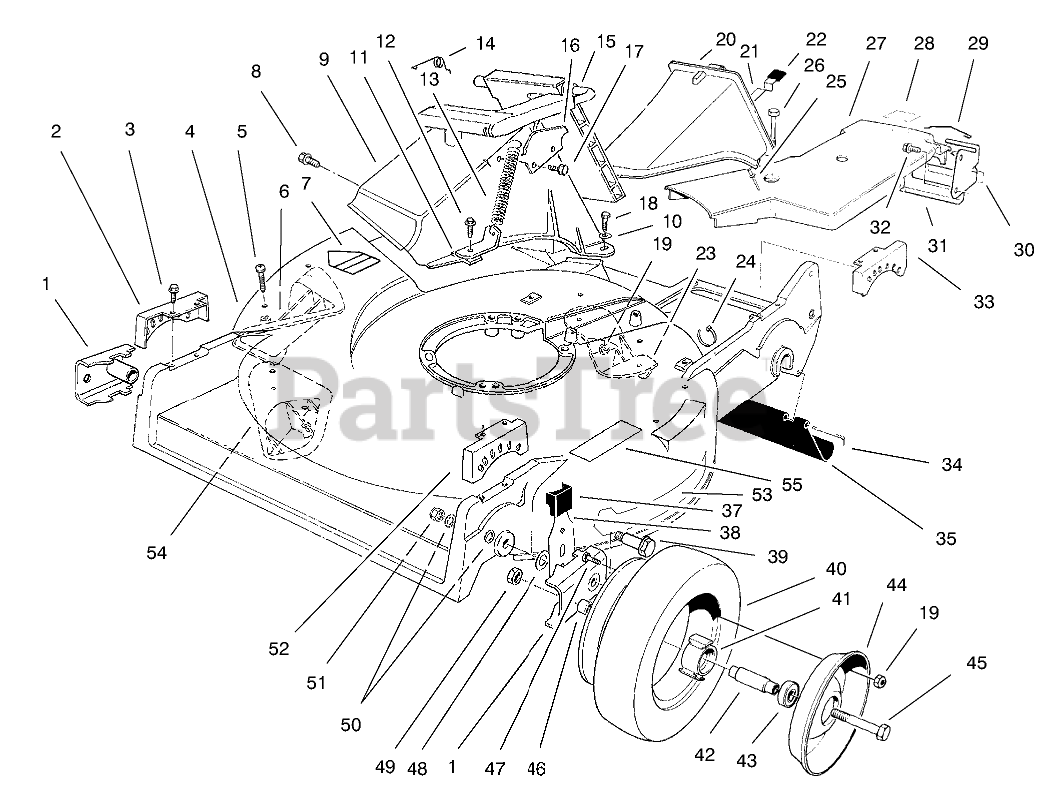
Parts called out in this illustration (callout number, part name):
1	ARM-PIVOT, FRONT
2	QUADRANT-FRONT, RH
3	SCREW-HWHTF
4	Housing-Commercial (Incl. Ref. # 5-7, 23, & 54-55)
5	SCREW-PPH
6	KICKER-RH
7	DECAL-DANGER
8	SCREW AND WASHER ASM
9	TUNNEL-DISCHARGE
10	WASHER-FLAT
11	BRACKET-SPRING
12	SCREW-HWH
13	SPRING-DOOR
14	RETAINER-DOOR
15	DISCHARGE DOOR ASM
16	LATCH-PLATE
17	SCREW-PLASTITE
18	SCREW-HH
19	NUT-LOCK, NI
20	Plug-Discharge (Incl. Ref. #21, 22, & 25)
21	LATCH-PLUG, DISCHARGE
22	GRIP-LATCH
23	KICKER-REAR
24	TIE-CABLE
25	RIVET-HEAD, FLAT
26	SCREW-HHFTF
27	COVER-BELT
28	LABEL-GREASE
29	RETAINER-CABLE
30	DECAL-POSITION, GEAR
31	BRACKET-ADJUSTMENT, TRACTION
32	SCREW-HWHTF
33	QUADRANT-REAR, LH
34	ROD-SHIELD
35	SHIELD-TRAILING
37	KNOB-ARM
38	FRONT SPRING ARM ASM
39	BOLT-WHEEL
41	HUB-BEARING
42	SPACER-BEARING
43	BEARING-WHEEL
44	Wheel-Half
45	SCREW-HH
46	SPACER-WHEEL
47	SCREW-HH
48	WASHER-THRUST
49	NUT-LOCK, CONE
50	WASHER
51	NUT-LOCK
52	QUADRANT-FRONT, LH
53	DECAL-RECYCLER
54	KICKER-FRONT
55	DECAL-INSTRUCTION, SAFETY
